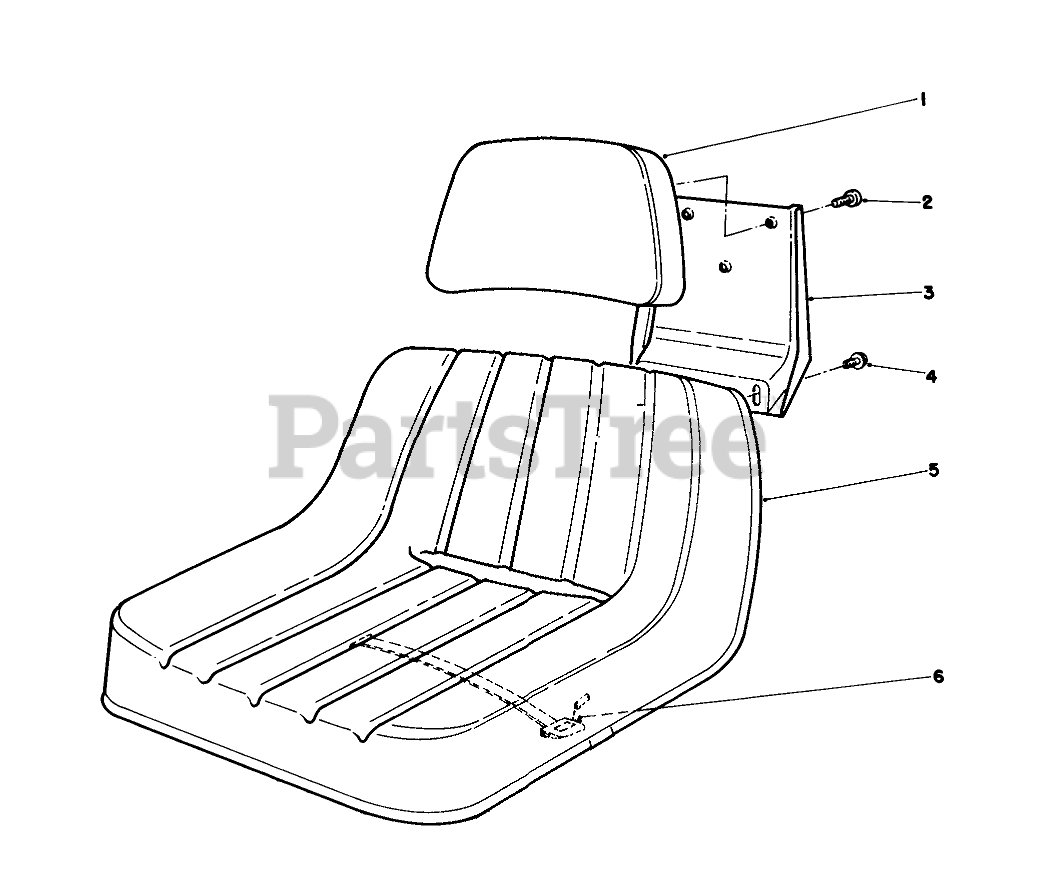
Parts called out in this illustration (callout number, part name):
1	Back Rest
2	SCREW-HEAD, PAN
3	PLATE
4	SCREW-HHF
5	Seat
6	SWITCH-SEAT
